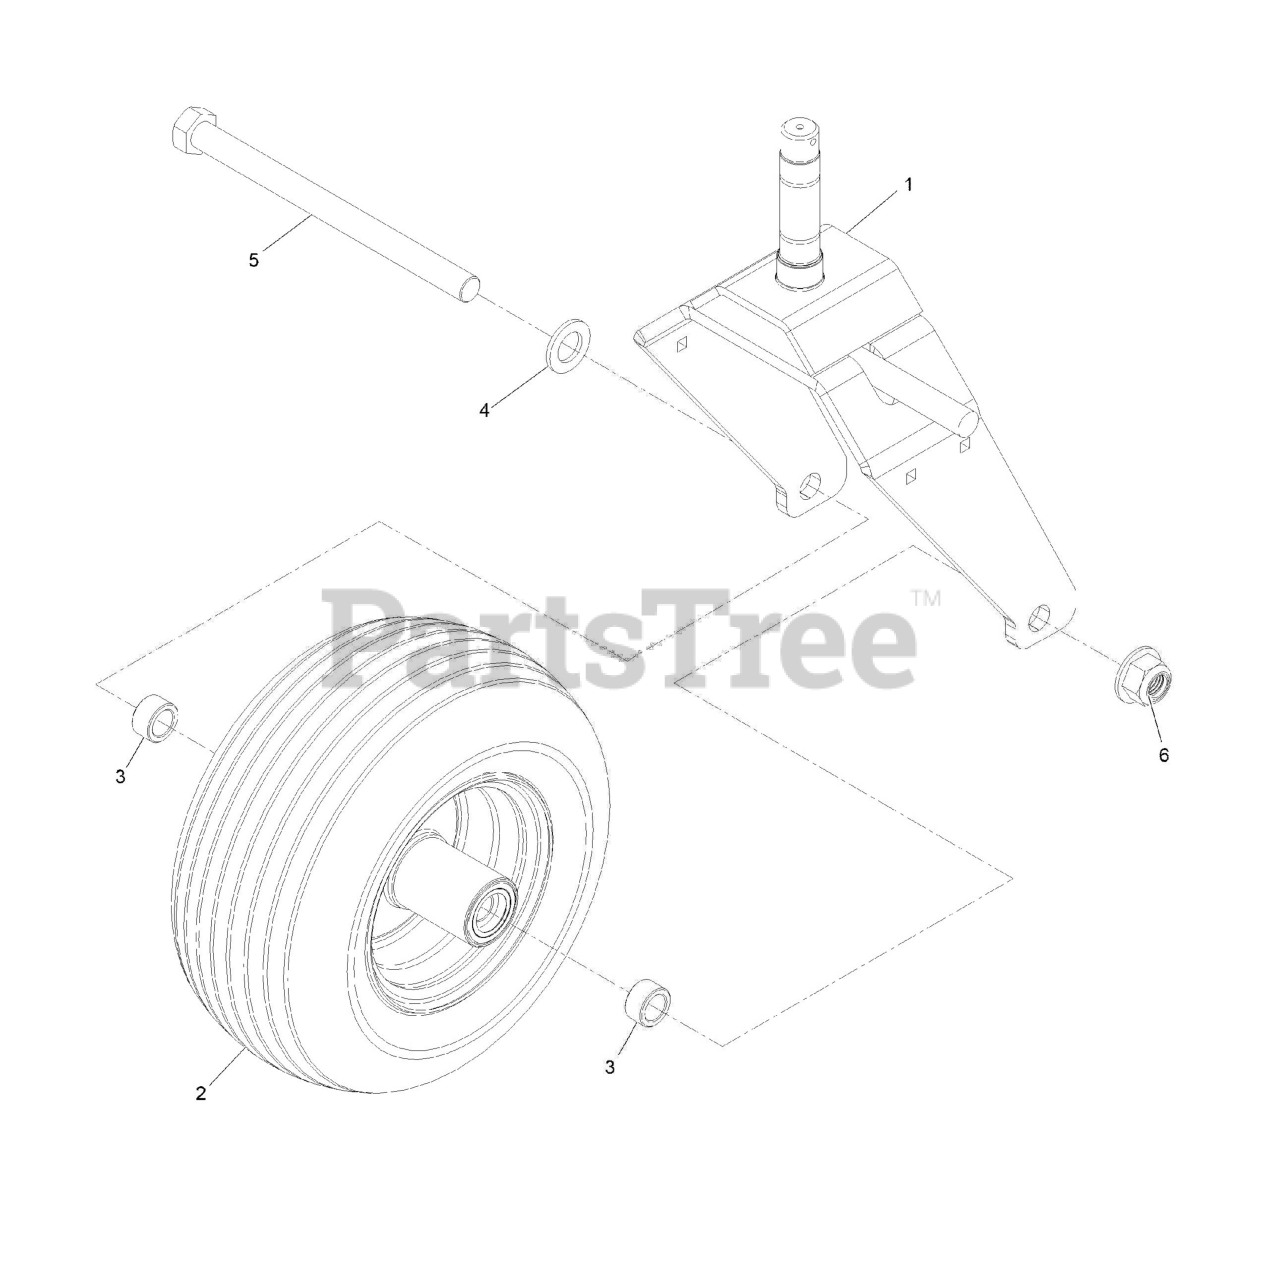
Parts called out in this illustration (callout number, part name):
1	Fork-Caster, RH [red]
2	WHEEL AND TIRE
3	SPACER-AXLE
5	SCREW-HH
